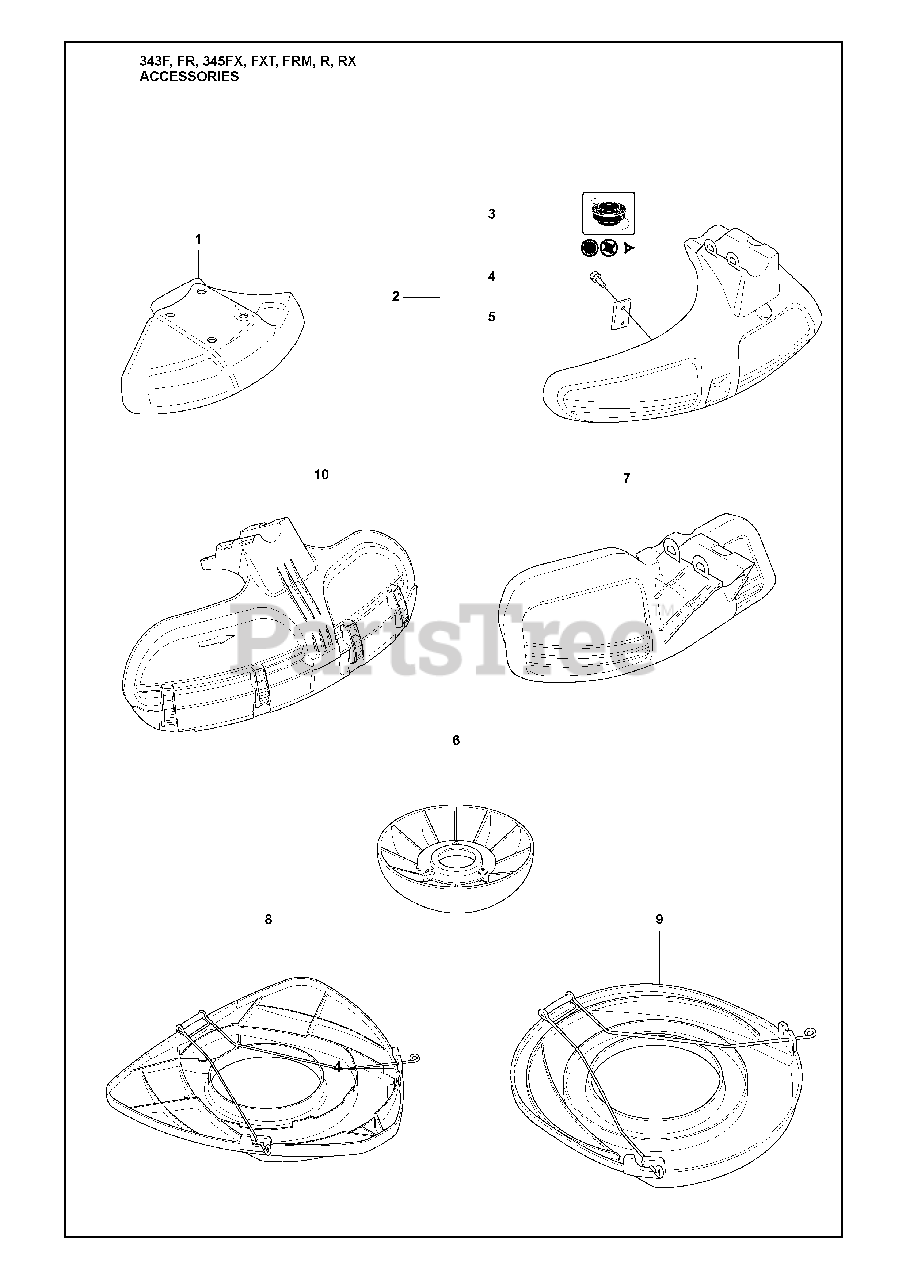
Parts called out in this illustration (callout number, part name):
1	BLADE GUARD SAW
1	RP BLADE GUARD
2	BLADE GUARD
5	LINE CUTTER
6	SUPPORTING CUP
7	BLADE GUARD
8	TRANSPORT GUARD
9	BLADE GUARD TRANSPORT
10	COMBINATION GUARD
